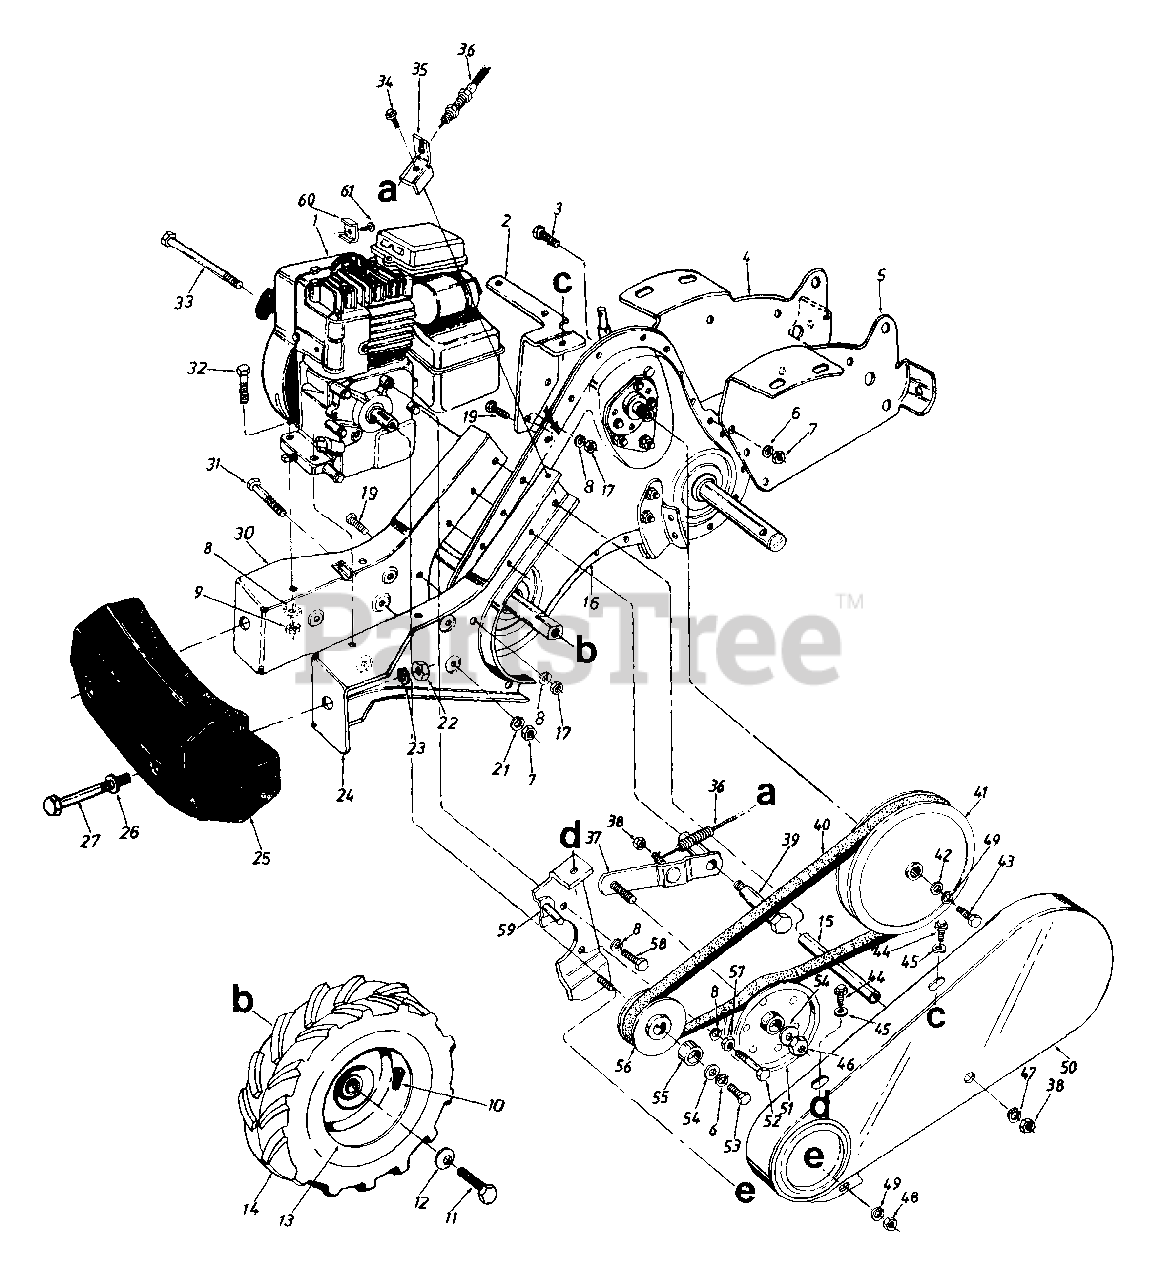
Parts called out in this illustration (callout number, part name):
1	Engine
4	Tine Shield Mtg. Brkt. - R.H.
7	Hex Nut 3/8-16 Thd.
8	L-Wash. 5/16" I.D.
9	Hex Nut 5/16-18" Thd.
10	Air Valve
11	Hex Bolt 5/16-24 x .62" Lg.
12	Bell-Wash. .345" I.D. x .88"
13	Wheel Rim Ass'y. Only
14	L.H. Wheel Ass'y. Comp.
14	R.H. Wheel Ass'y. Comp.
14	Tire Only 13 x 5.0
15	Spacer 3/8" I.D. x 3.38" Lg.
16	Transmission Comp.
17	Hex Nut 5/16-18 Thd.
19	Hex Bolt 5/16-18 x .75" Lg.
21	L-Wash. 3/8" I.D. - H.D.
22	Hex Nut 1/2-13 Thd.
23	L-Wash. 1/2" I.D.
26	Fl-Wash. .510" I.D. x 1.0"
27	Hex Bolt 1/2-13 x 5.00" Lg.
32	Hex Bolt 5/16-18 x 1.50"
33	Hex Bolt 5/16-18 x 4.75" Lg. - Gr. 2
34	Hex Wash. TT-Tap Scr. 5/16-18 x .62" Lg.
35	Bracket Clutch Cable
36	Clutch Control Cable 53" Lg.
39	Shld. Bolt .500" Dia. x 2.27"
40	V-Belt
41	V-Pulley Split 5/8" I.D.
42	Fl-Wash. 1/4" I.D. x .93" O.D.
43	Hex Bolt 1/4-28 x .75" Lg.
44	Hex Wash. Hd. S-Tap Scr. 1/4-20 x .50" Lg.
45	Fl-Wash. .281" I.D. x .625"
46	Hex Cent. L-Nut 3/8-24 Thd.
47	Fl-Wash. 5/16" I.D.
48	Hex Nut 1/4-20 Thd.
49	L-Wash. 1/4" I.D.
51	Fl-Idler w/Flanges 3.75" O.D.
52	Hex Bolt 5/16-24 x 1.75"
53	Hex Bolt 3/8-24 x 1.00" Lg.
54	Fl-Wash. 3/8" I.D. x 1.00"
55	Spacer .758" I.D. x .990"
56	Engine Pulley
57	Hex Nut 5/16-24 Thd.
58	Hex Bolt 5/16-24 x .62" Lg.
61	Hex Sems Scr. #10-32 x .62"
